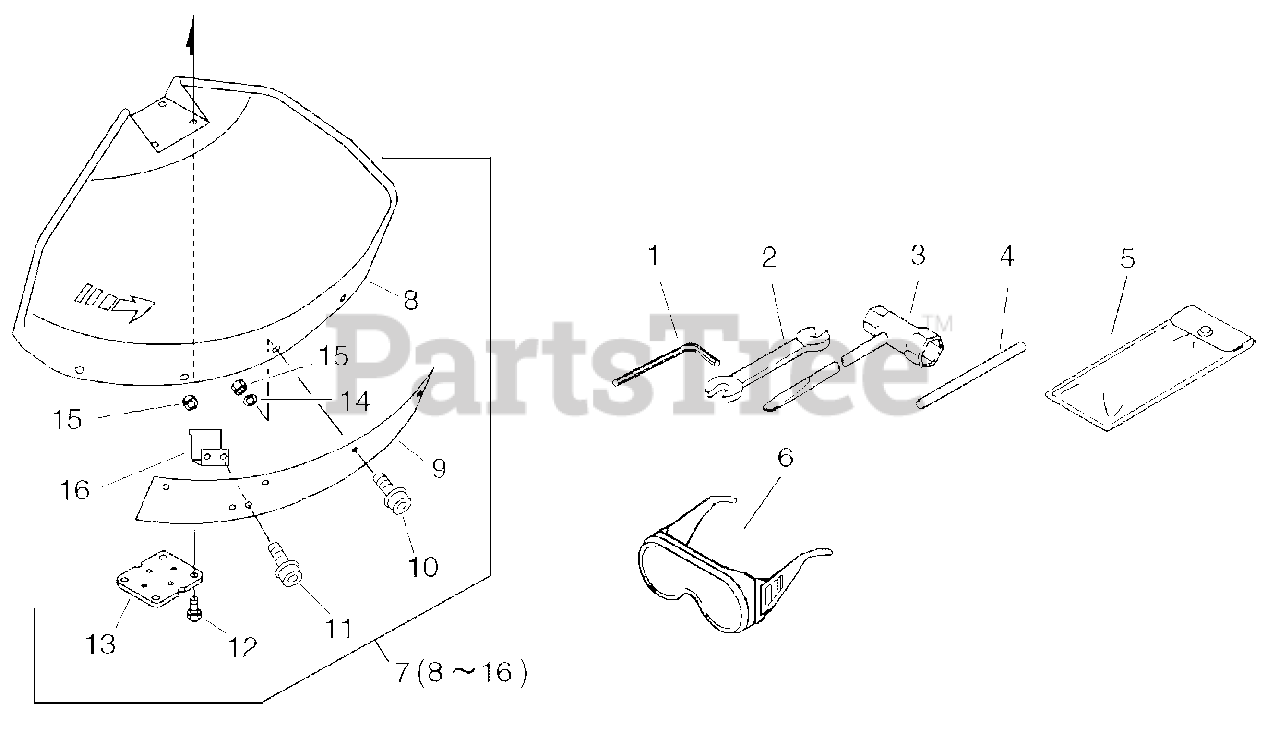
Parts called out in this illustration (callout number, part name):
1	HEX KEY - 4mm
2	SPANNER - 8X10mm
3	T-WRENCH - 17X19mm
4	LOCKING TOOL
5	BAG, TOOL
6	GOGGLES
7	SHIELD ASSY
8	SHIELD, DEBRIS
9	GUARD, SHIELD
10	SCREW - 5X18
11	SCREW - 5X14
12	SCREW - 5X25
13	BRACKET, SHIELD
14	WASHER - 5
16	KNIFE, TRIMMER LINE
